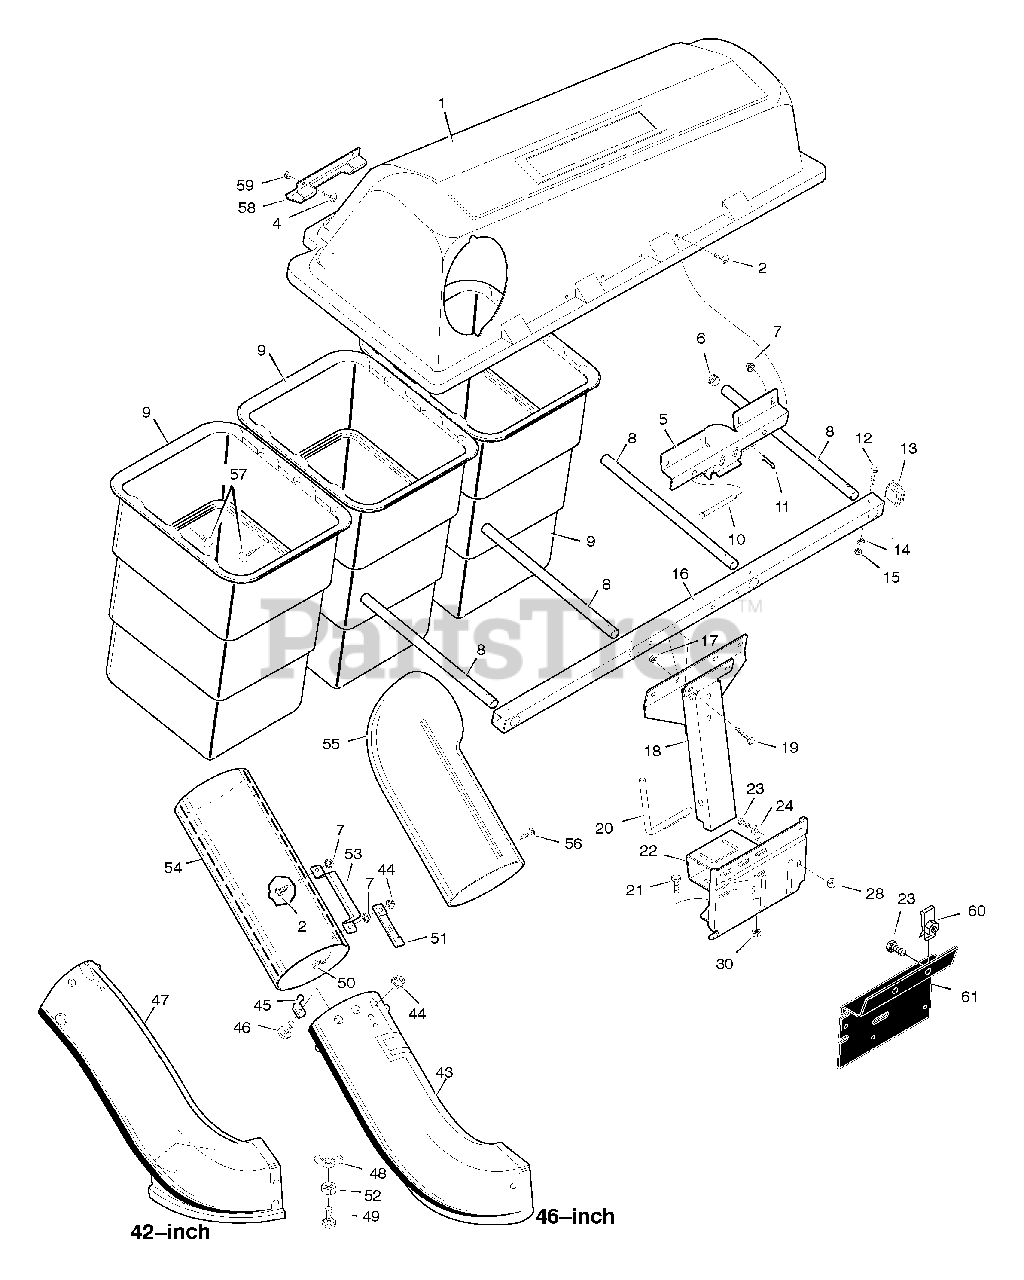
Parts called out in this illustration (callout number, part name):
1	Cover, Bagger
5	Hinge, Bracket
7	Nut, Hex
8	Tube, Container
9	Container
10	Pin, Cover Hinge
11	Pin, Hair
14	Lockwasher
16	Tube, Support
17	Nut
18	Assembly, Channel
20	Pin, Channel Mount
21	Bolt, Hex
22	Assembly, Bagger Mount
23	Bolt, Hex
28	Nut, Super Flange
30	Nut, Hex
43	Extension, Chute 46"
44	Locknut, Flange
45	Pin, Latch
46	Bolt, Carriage
47	Extension, Chute 42"
48	Wingnut
49	Bolt, Carriage
51	Latch, Rubber
53	Handle, Connector Tube
54	Tube, Connecting
55	Elbow
57	Fastener, Panel
58	Handle, Plastic
59	Nut, Hex
61	Bracket, Adapter
